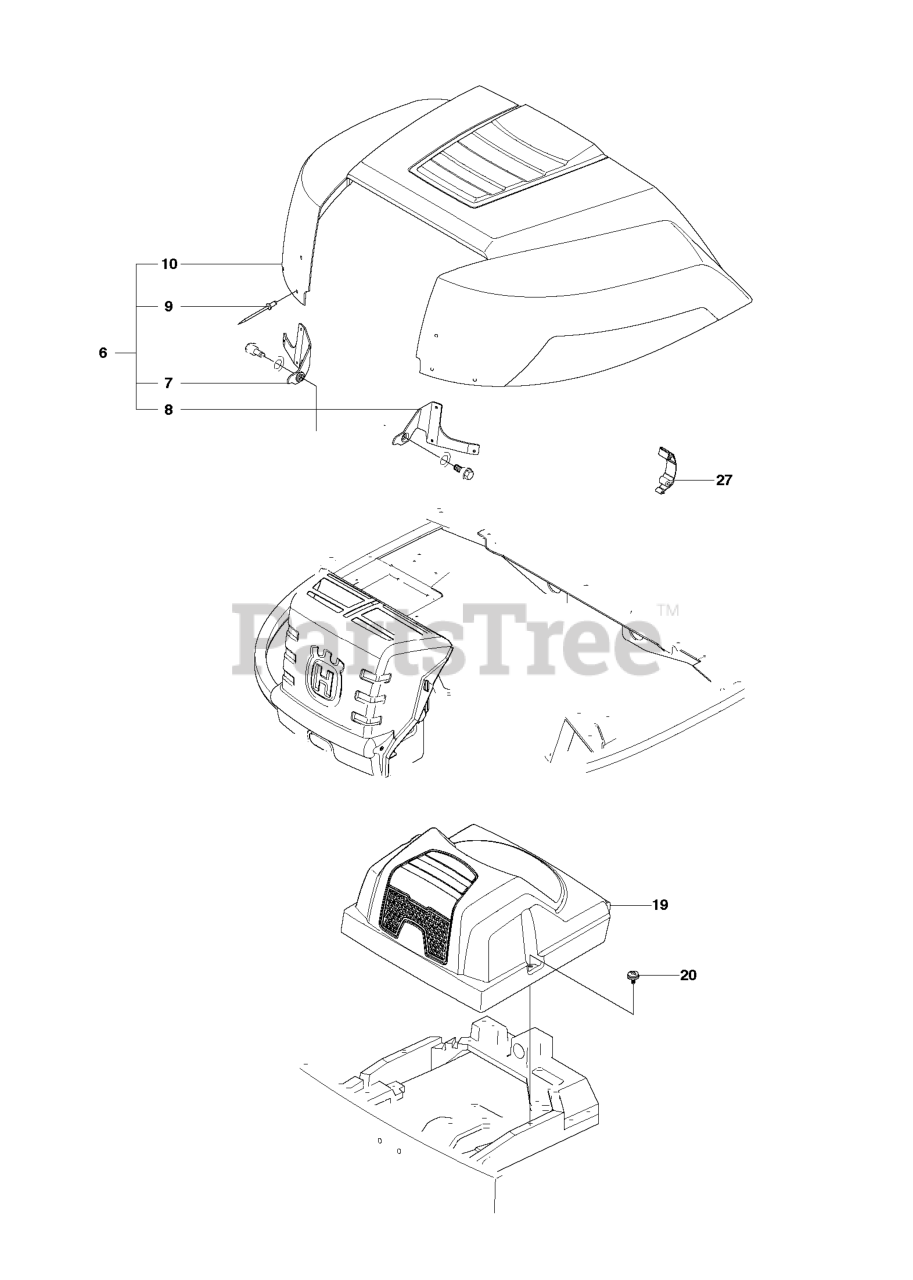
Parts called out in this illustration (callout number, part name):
10	ENGINE HOOD ASSY
19	COVER
27	CLIP GRAY
